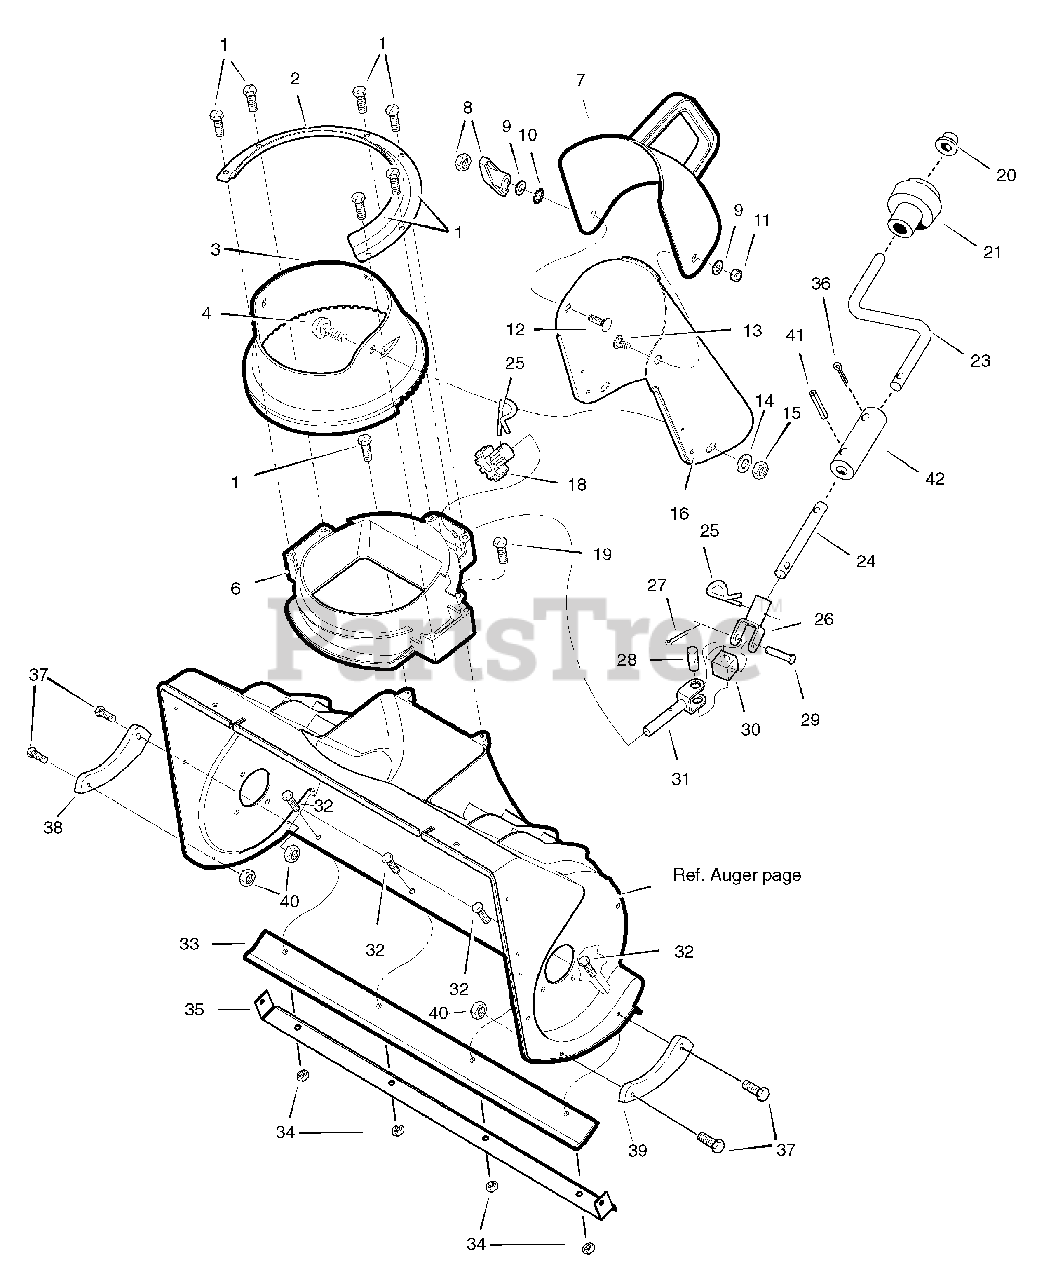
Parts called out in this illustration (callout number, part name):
1	SCREW, 1/4-14
2	RETAINER, Chute Ring
3	RING, Chute
4	BOLT, Carriage, 5/16-18 x 3/4
6	NECK, Chute
7	CHUTE, 22" Upper
9	WASHER, 11/32 x 11/16 OD
10	LOCKWASHER, Shakeproof
11	LOCKNUT, Hex, 5/16-18
12	BOLT, Carriage, 5/16-18
13	BOLT, Upper Chute
14	WASHER, Flat, 11/16
15	NUT, Nylock, 5/16-18
16	CHUTE, Lower
19	SCREW, 1/4-14 x 3/4
21	KNOB, Sleeve
23	CRANK, Chute Rotation
24	HANDLE, Chute Rotator, Lower
26	YOKE ASSEMBLY, Adapter
27	PIN, Cotter, 1/2
28	PIN, Universal Joint
29	PIN, Clevis
30	HOUSING, Universal
31	ROD, Lower Crank
32	SCREW, 1/4-20 x 3/4
33	BLADE, Scraper
34	LOCKNUT, Hex, 1/4-20
35	PLATE, Reinforcement
36	CLIP, Hairpin, 3/32 x 1-5/8"
37	SCREW, Torx, 10-32 x 3/4
38	SKID SHOE, R.H.
39	SKID SHOE, L.H.
40	NUT, Nylock, 10-32
41	PIN, Spring, 5/32 x 1"
42	SPLICE, Chute Handle
